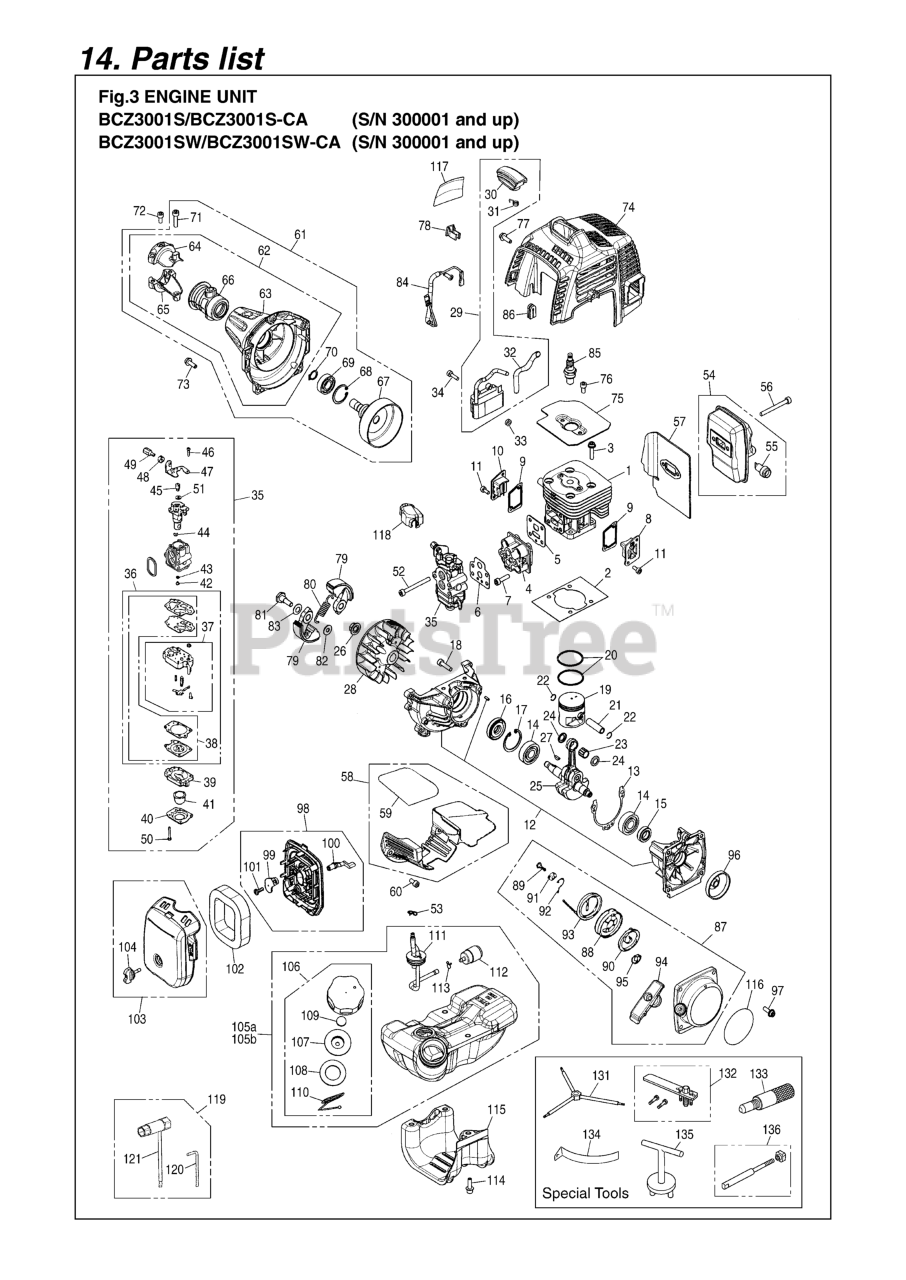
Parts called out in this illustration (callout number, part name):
1	CYLINDER (RPLS 848-F60-12A2)
2	GASKET, BASE
3	BOLT
4	INSULATOR
5	GASKET, INSUL (RPLS.T1590-131200)
6	GASKET, CARBURETOR
7	BOLT, TORX
8	COVER, TRS
9	GASKET, TR
10	COVER,TRF (REPLACES -12D1)
11	BOLT, TORX
12	CRANKCASE-C
13	GASKET, CASE
14	BEARING
15	SEAL
16	SEAL, OIL (RPLS 1200-21220)
17	RING, SNAP, M32 x 1.2
18	BOLT (RPLS 2850-14220)
19	PISTON
20	RING
22	RING, SNAP
23	BEARING
24	WASHER (RPLS 3310-41341)
25	CRANKSHAFT-C
27	KEY
28	ROTOR
29	COIL-A
30	CAP
31	SPRING
33	SPACER (RPLS -71260)
34	BOLT TORX
35	CARBURETOR ASSY
36	REBUILD KIT
37	BODY, PUMP
38	KIT, GASKET (REPLACES-06020)
39	BODY, PURGE
40	COVER, PUMP
41	PUMP, PRIMING
42	JET (REPLACES 4810-81250)
43	RING, O
44	RING
45	SWIVEL
46	SCREW
48	NUT, CABLE ADJUSTER
49	SCREW, CABLE ADJUSTER
50	SCREW
51	WASHER
52	BOLT
53	CLIP
54	MUFFLER ASSY
55	ARRESTER
56	BOLT
57	GASKET, MUFFLER
58	PLATE-A
59	SHEET
60	BOLT
61	HOUSING ASSY
62	HOUSING COMP.
63	HOUSING
64	BRACKET (A) (RPLS -31211)
65	BRACKET (B)
66	CUSHION (RPLS -31231)
67	DRUM (REPLACES 4810-31122)
68	RING, SNAP, M28 x 1.2
69	BEARING
70	RING, SNAP (RPLS 3130-13270)
71	BOLT (RPLS 2850-14220)
72	BOLT
73	BOLT
74	COVER, ENGINE
75	PLATE, CYL
76	BOLT
77	BOLT, TORX
78	CLAMP
79	SHOE
80	SPRING
81	BOLT
82	WASHER, FLAT (USE 182303)
83	WASHER (RPLS -51241)
84	CORD COMP.
85	SPARK PLUG
86	GROMMET
87	RECOIL-A
88	REEL
89	SCREW
90	SPRING, SPIRAL
91	COLLAR
92	ARM
93	ROPE (REPLACES 4500-75160)
94	KNOB (RPLS -75420)
95	PLATE, STOPPER
96	PULLEY
97	BOLT, TORX
98	BODY ASSY (RPLS T1551-82100)
99	PLATE, CHOKE
100	LEVER
101	SCREW
102	ELEMENT
103	COVER-A (RPLS T1551-82200)
104	KNOB
105A	TANK ASSY
106	CAP ASSY (RPLS -85201)
107	HOLDER (REPLACES -85230)
108	PACKING
109	FILTER
110	STOPPER
112	FILTER ASSY
113	CLIP
114	BOLT (USE 848-815-2000)
115	GUARD, TANK
116	LABEL, RECOIL
117	LABEL, COVER
118	COVER
119	TOOL SET
120	BAR
121	SOCKET
131	WRENCH (RPLS. 2670-96410)
132	PULLER ASSY
133	STOPPER (TOOL)
134	GUAGE, AIR GAP (TOOL)
135	PULLER, RECOIL (TOOL)
136	ROD-A
